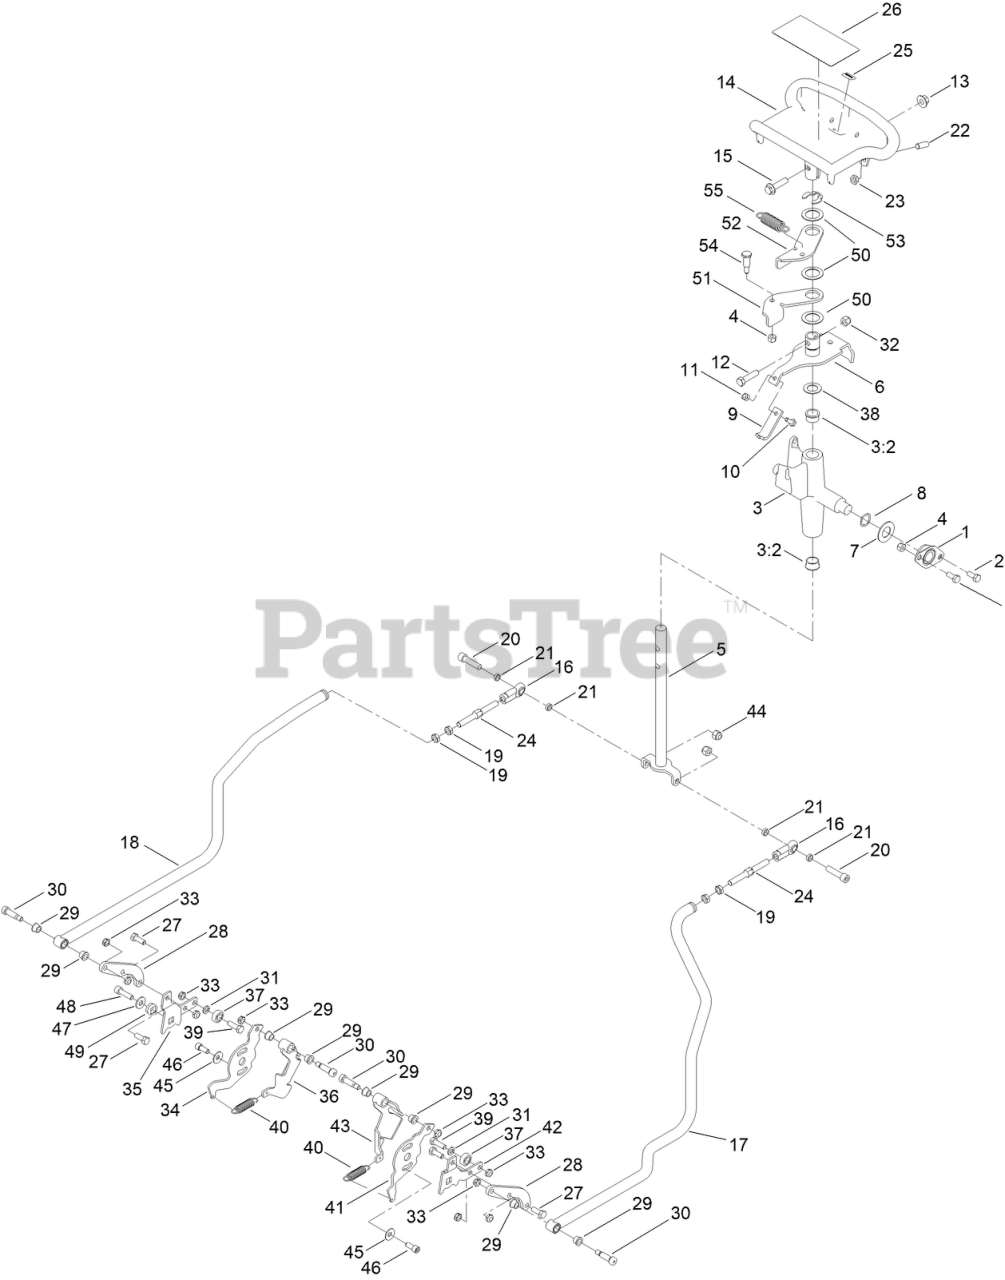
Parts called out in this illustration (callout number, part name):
1	BEARING
2	SCREW-HH
3	CONTROL SUPPORT ASM
3:2	BEARING-FLANGE
4	NUT-LOCK, NI
5	ROD-DRIVE
6	LEVER-PIVOT
7	WASHER-FLAT
8	WASHER-SPRING, WAVE
9	PLATE-NEUTRAL
10	SCREW-HH
11	NUT-LOCK, NI
12	SCREW-HH
13	NUT-FLANGE
14	HANDLE-CONTROL [BLK-TXT]
15	SCREW-HHF
16	JOINT-BALL END, LH
17	ROD-CONTROL, LH
18	ROD-CONTROL, RH
19	NUT-HJ
20	SCREW-HSH
21	SPACER-PLATE, RETAINING
22	SCREW-SET
23	NUT-JAM
24	LINK-CONTROL, ADJUSTMENT
25	DECAL
26	DECAL-TRACTION
27	SCREW-HH
28	PLATE-ADAPTER, CONTROL, RH
29	BUSHING-FLANGE
30	BOLT-SHOULDER
31	WASHER-LOCK
32	NUT-LOCK, NI
33	NUT-LOCK, NI
34	PLATE-BASE, RH
35	PLATE-ARM, RETURN
36	PIVOT-RH
37	BEARING-BALL
38	WASHER-THRUST
39	SCREW-HH
40	SPRING-EXTENSION
41	PLATE-BASE, LH
42	PLATE-ARM, RETURN, LH
43	PIVOT-LH
44	NUT-LOCK, NI
45	WASHER-BELLEVILLE
46	SCREW-HSH
47	WASHER-FLAT
48	SCREW-HSH
49	LOCK-TRUNION
50	WASHER-PLAIN
51	LEVER-RETURN, RH
52	LEVER-RETURN, LH
53	RING-RETAINING
54	SCREW-SHOULDER
55	SPRING-EXTENSION
